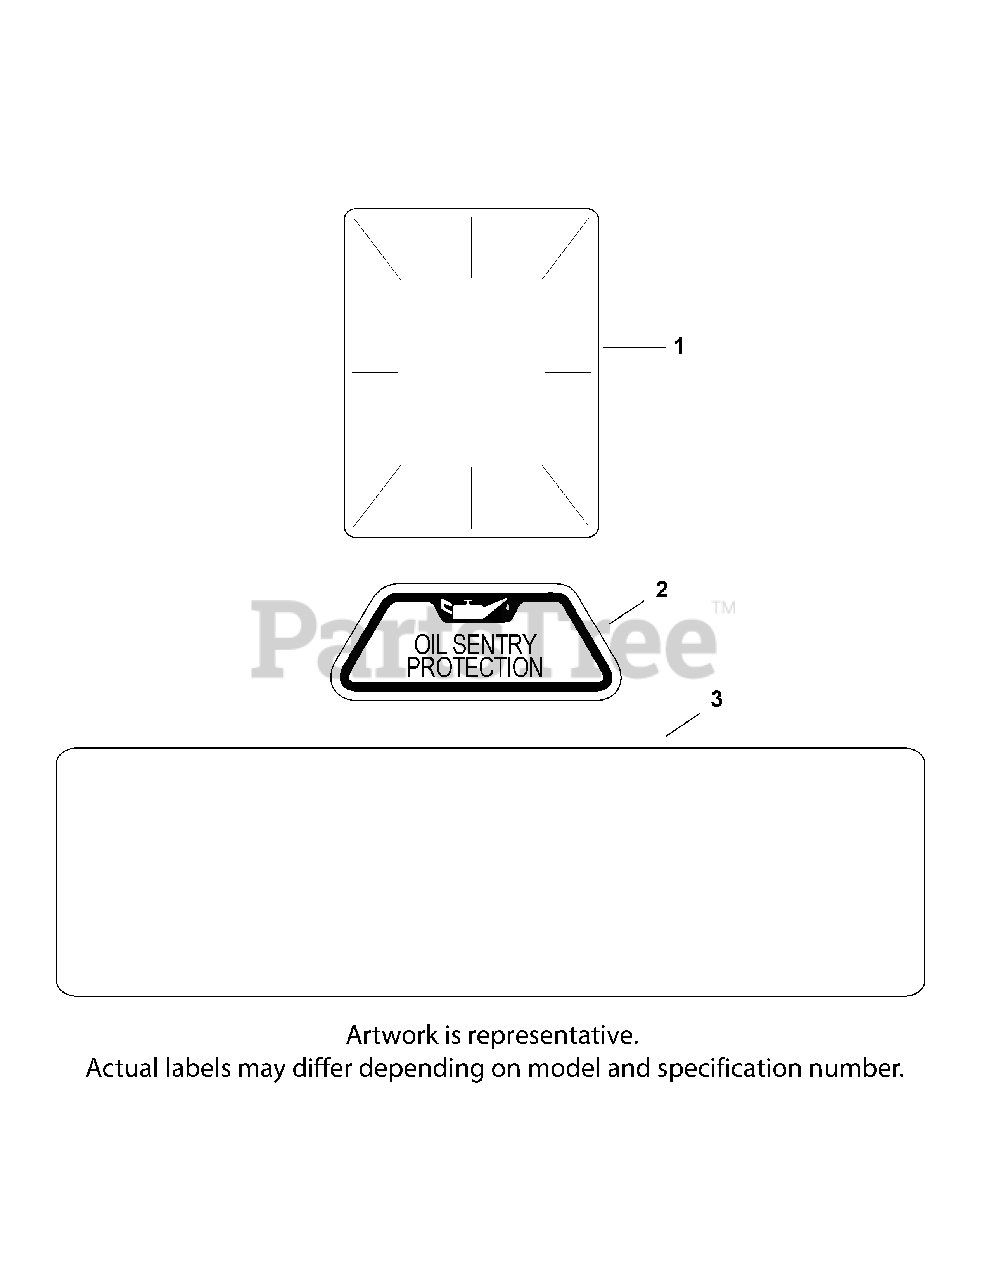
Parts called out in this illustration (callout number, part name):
1	Decal, Clear Laminate
2	Decal, Oil Sentry
3	Decal,HP (20)
